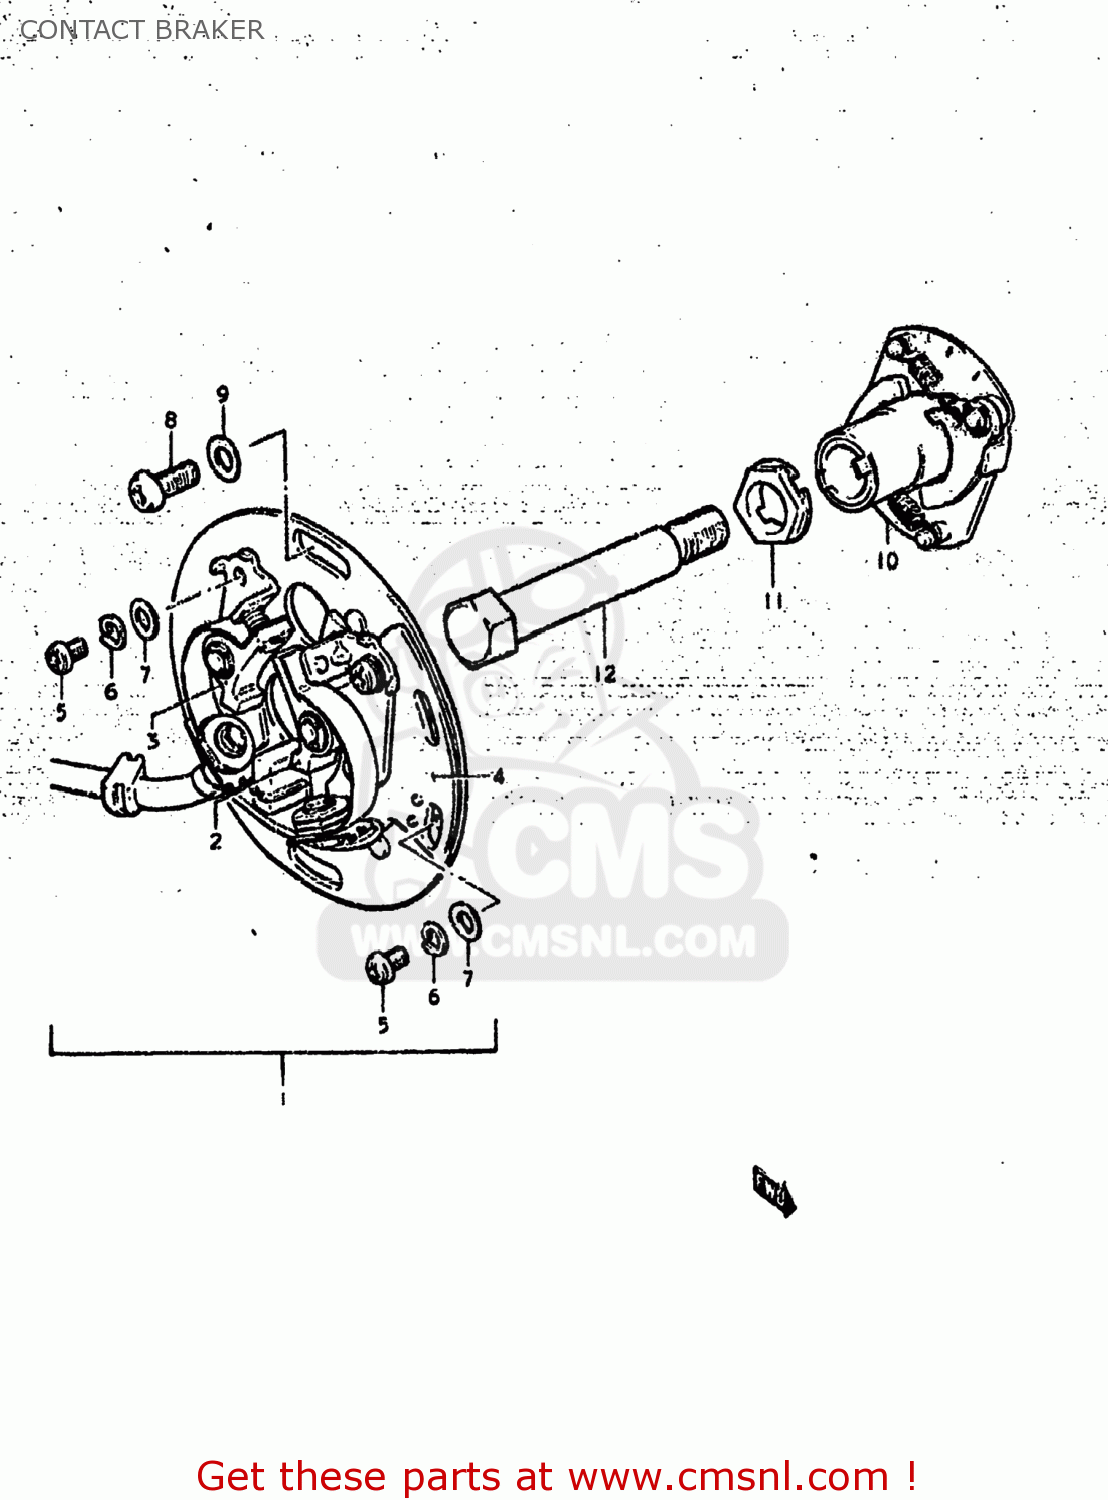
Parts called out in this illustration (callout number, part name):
1	SIGNAL GENERATOR ASSEMBLY
2	POINT ASSEMBLY,CONTACT
3	POINT ASSEMBLY,CONTACT
4	PLATE,CONTACT POINT
5	SCREW(4X10)
6	LOCK WASHER
7	WASHER
8	SCREW(5X12)
9	WASHER 5MM
10	GOVERNOR ASSEMBLY
11	WASHER
12	BOLT
